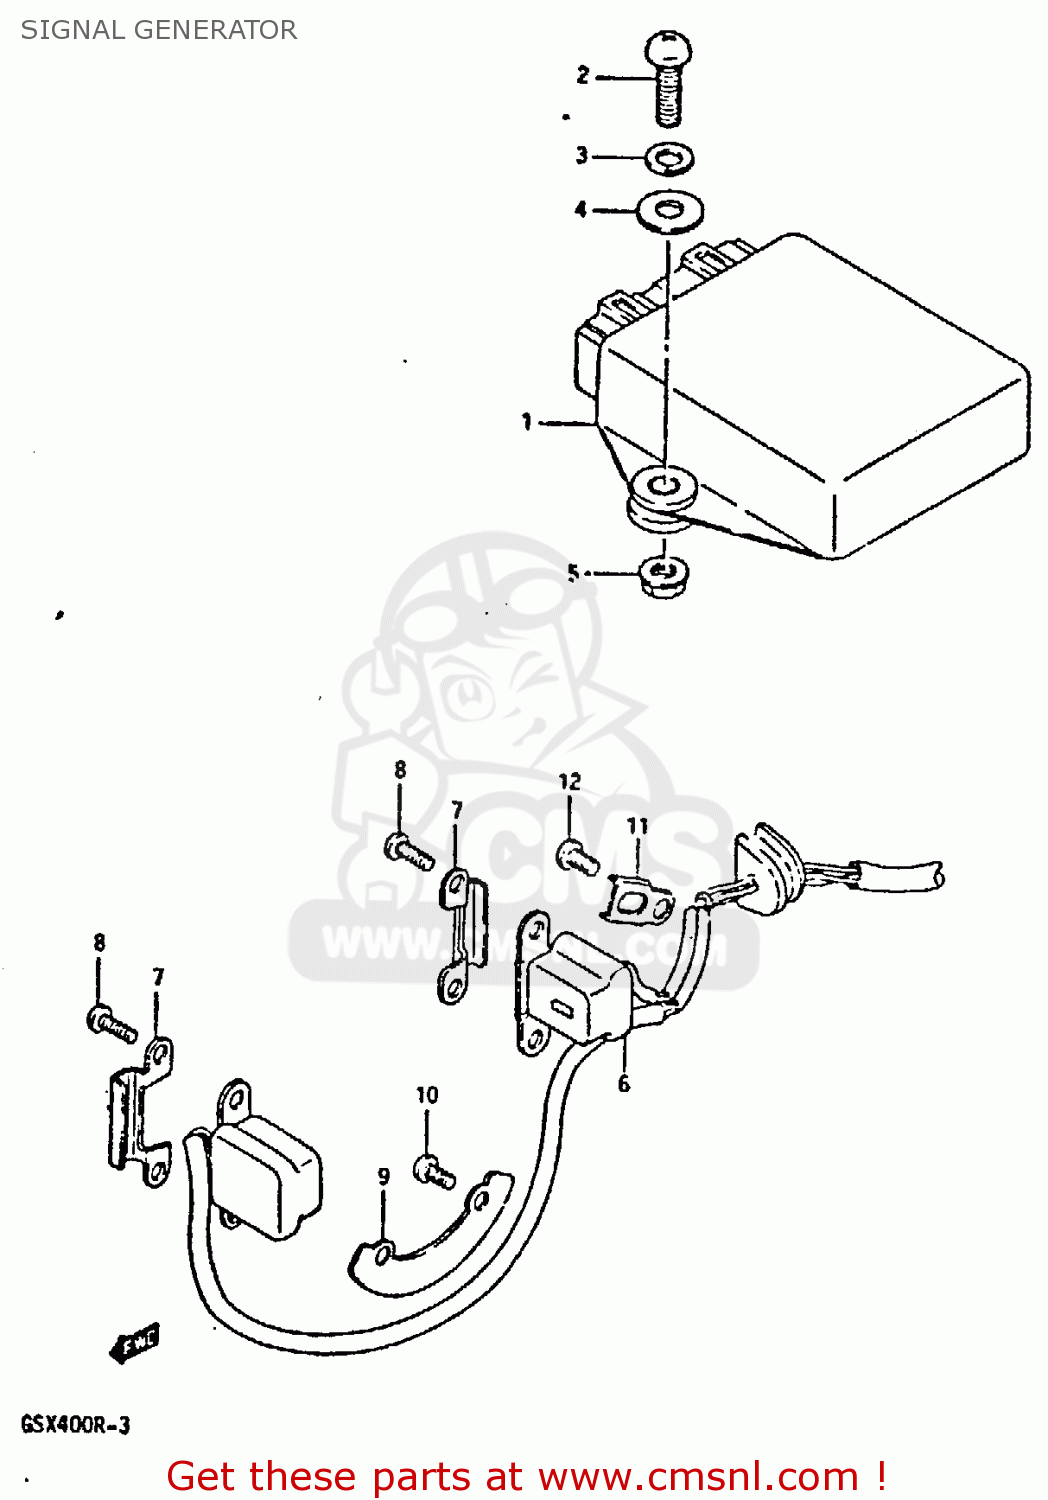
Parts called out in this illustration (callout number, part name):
1	IGNITER UNIT A
2	SCREW
3	WASHER,LOCK
4	WASHER
5	NUT
6	SIGNAAL.GENER.
7	PROTECTOR,SIGNAL GEN LEAD WIRE
8	SCREW 4X10
10	SCREW
11	CLAMP,GENERATOR LEAD WIRE
12	SCREW
